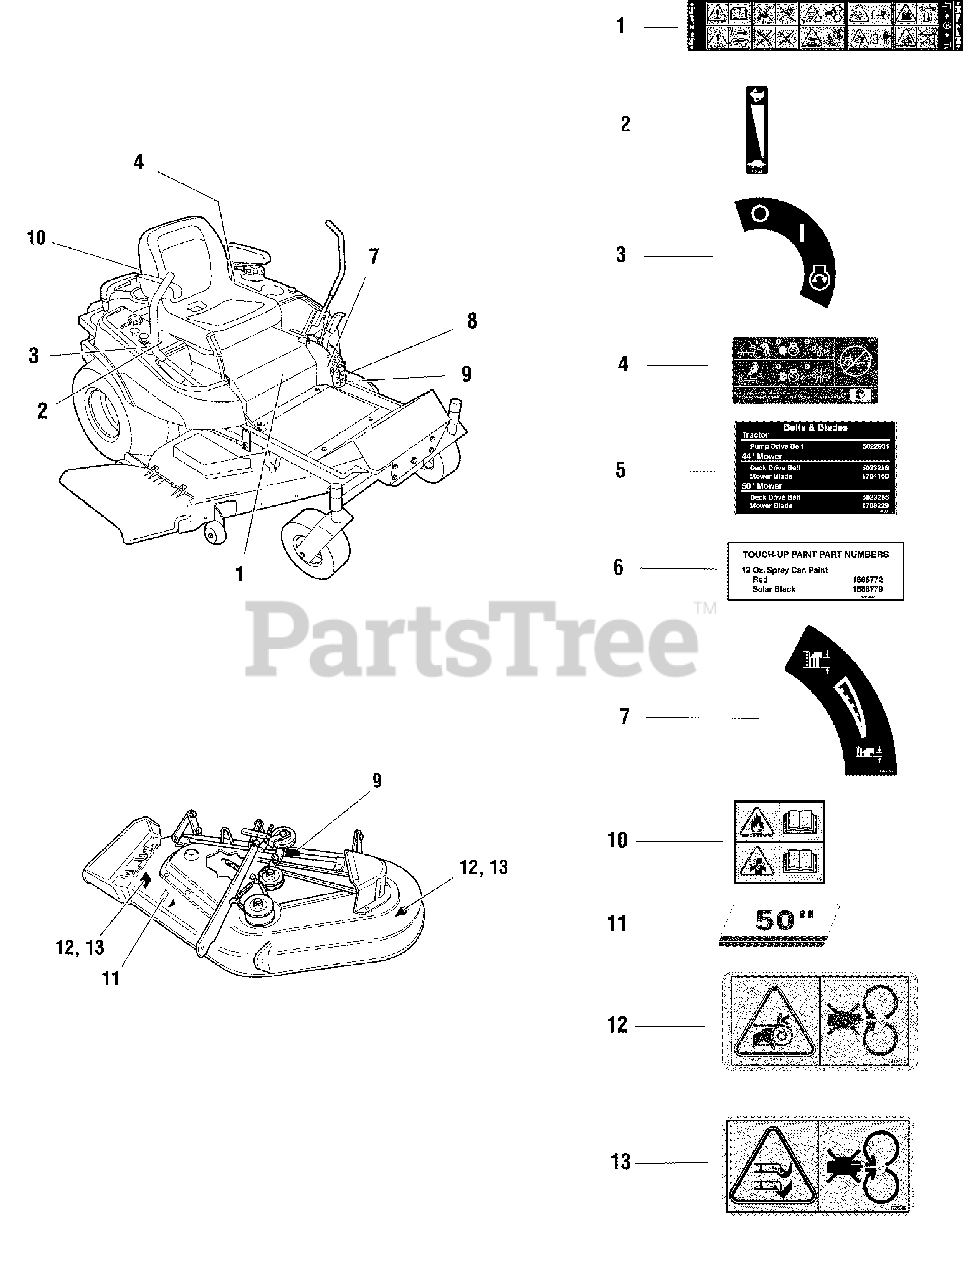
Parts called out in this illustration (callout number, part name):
1	DECAL, MAIN CE
2	DECAL, THROTTLE CONTROL
3	DECAL, IGNITION SWITCH
4	DECAL, CZT HYRDO RELEASE
5	DECAL, BELT & BLADE
6	DECAL, TOUCH UP PAINT ORANGE,BLACK,RED
7	DECAL, HEIGHT OF CUT
8	DECAL, US PATENT, ZTR
9	DECAL, ID PLATE
10	DECAL, DANGER, CE
11	DECAL, 50"- SILVER ON BLACK W/STRIPE
12	DECAL, CE DANGER
13	DECAL, DANGER ROTATING BLADE SYMBOLS
